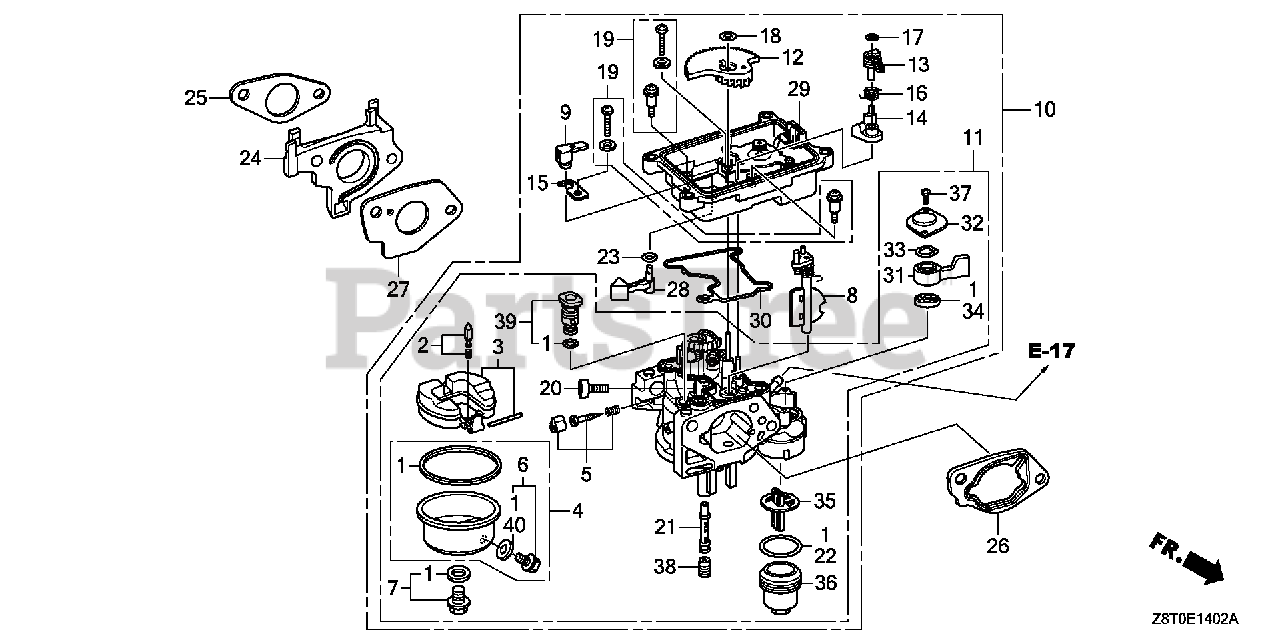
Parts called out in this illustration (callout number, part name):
1	GASKET SET (INCLUDES 16173-001-004)
2	VALVE SET, FLOAT
4	CHAMBER SET, FLOAT
5	SCREW SET, PILOT
6	SCREW SET, DRAIN
9	ARM, MANUAL START
10	CARBURETOR ASSY. (BE91A A)
11	CARBURETOR SET
12	GEAR, MIDDLE
13	ARM, CHOKE
14	LEVER, CHOKE CONTROL
16	SPRING, TORSION COIL
17	CLIP, SPECIAL
18	CLIP, SPECIAL
20	SCREW, STOP
21	NOZZLE, MAIN
22	GASKET, FUEL STRAINER CUP
24	INSULATOR, CARBURETOR
25	GASKET, CARBURETOR INSULATOR
26	SPACER, CARBURETOR
27	GASKET, CARBURETOR
28	LEVER, MANUAL START
29	CASE, MOTOR
31	LEVER, PETCOCK
32	PLATE, LEVER SETTING
33	SPRING, PETCOCK LEVER
34	GASKET, PETCOCK
35	FILTER, CUP
36	CUP, FUEL STRAINER
37	SCREW, PAN (3X6)
38	JET, MAIN (#88)
38	JET, MAIN (#92)
38	JET, MAIN (#95)
38	JET, MAIN (#98)
39	JET SET, PILOT (#38)
